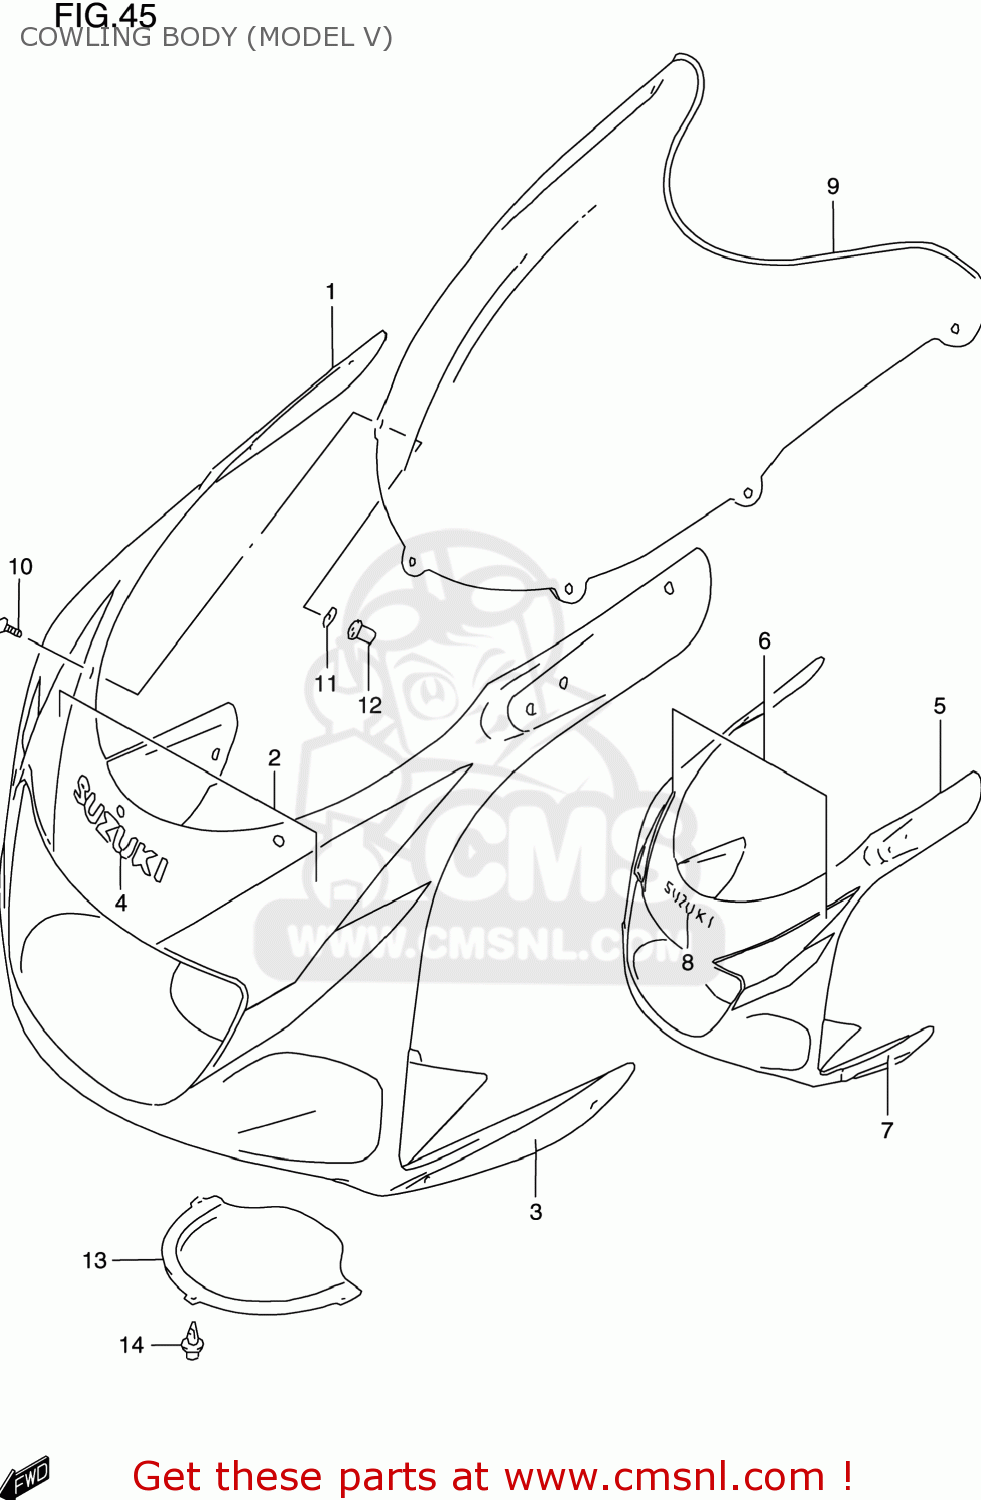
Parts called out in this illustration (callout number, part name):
1	COWLING ASSY,BODY
2	TAPE SET,COWL BODY FR
3	TAPE SET,COWL BODY SIDE
4	EMBLEM,COWLING UPR
5	COWLING ASSY,BODY
6	TAPE SET,COWL BODY FR
7	TAPE SET,COWL BODY SIDE
8	EMBLEM,SUZUKI
9	WINDSCREEN
10	SCREW(5X14)
11	WASHER
12	NUT
13	LID,BODY COWLING,LOWER
14	CLIP(BLACK)
